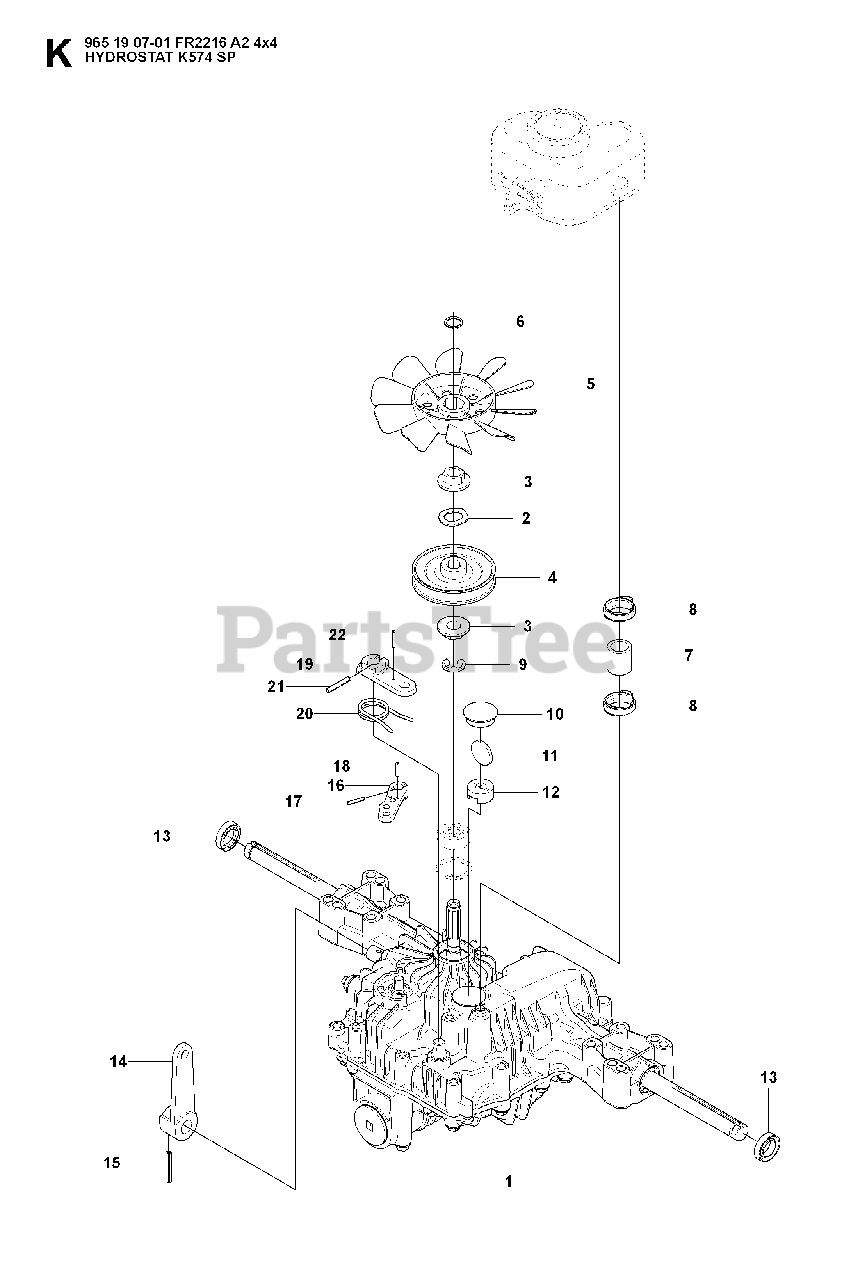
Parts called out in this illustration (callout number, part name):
1	HYDRAULMOTOR
2	WASHER **
5	FAN
6	RETAINING RING **
8	CLAMP
12	MAGNET HOLDER
13	SEALING
14	CONTROL LEVER
20	RETURN SPRING
